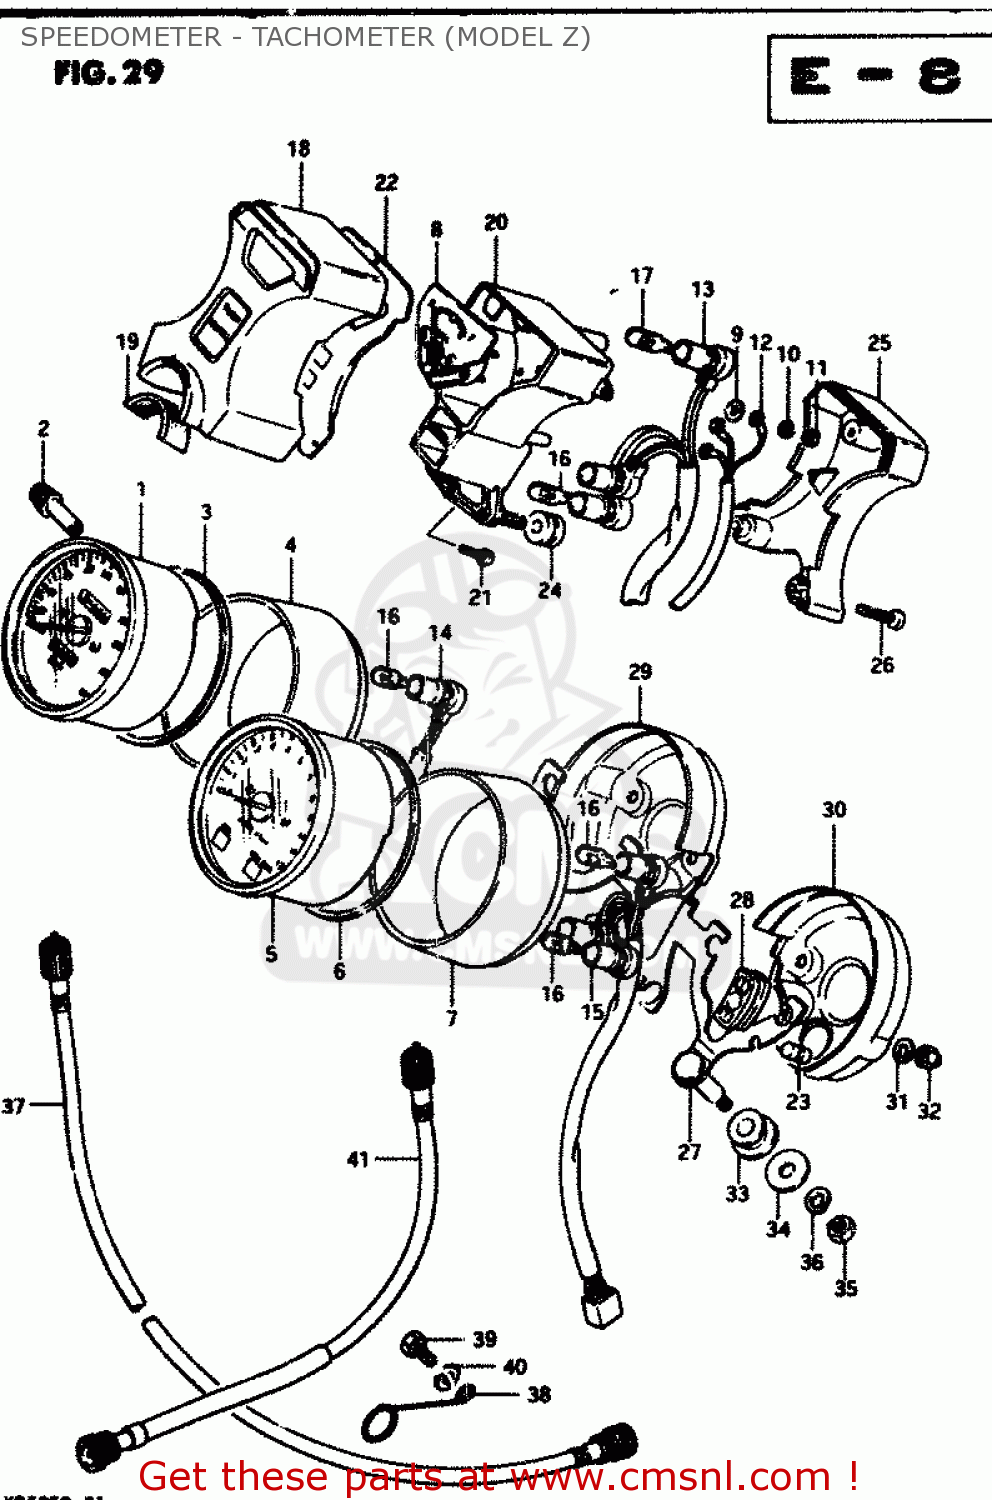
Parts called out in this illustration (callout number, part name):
1	SPEEDOMETER (KILO)
2	KNOB
3	CUSHION,SPEEDOMETER
4	COVER,SPEEDOMETER
5	TACHOMETER
6	CUSHION,SPEEDOMETER
7	COVER,TACHOMETER
8	FUELMETER
9	WASHER,FUEL METER
10	LOCK WASHER
11	NUT 3MM
12	LEAD WIRE, FUELMETER
13	SOCKET, PILOT LAMP
14	SOCKET,METER
15	SOCKET,TACHOMETER
16	BULB(12V3.4W,T10)
17	BULB(12V1.7W,T10,WB121)
18	CASE, PILOT BOX
19	SEAL,IGNITION SWITCH
20	BOX, PILOT
21	SCREW,INDICATOR
22	PANEL
23	CUSHION
24	CUSHION,PILOT BOX
25	COVER, PILOT BOX
26	SCREW
27	BRACKET,COMBINATION METER
28	CUSHION,METER
29	COVER,METER,UNDER
30	COVER,TACHOMETER
31	WASHER
32	NUT
33	CUSHION,METER BRACKET
34	WASHER (8.5X29X1.6)
35	NUT
36	LOCK WASHER
37	CABLE ASSY,SPEEDOMETER
38	CLAMP,SPEEDOMETER CABLE
39	BOLT, UPPER
40	WASHER
41	CABLE ASSEMBLY,TACHOMETER
